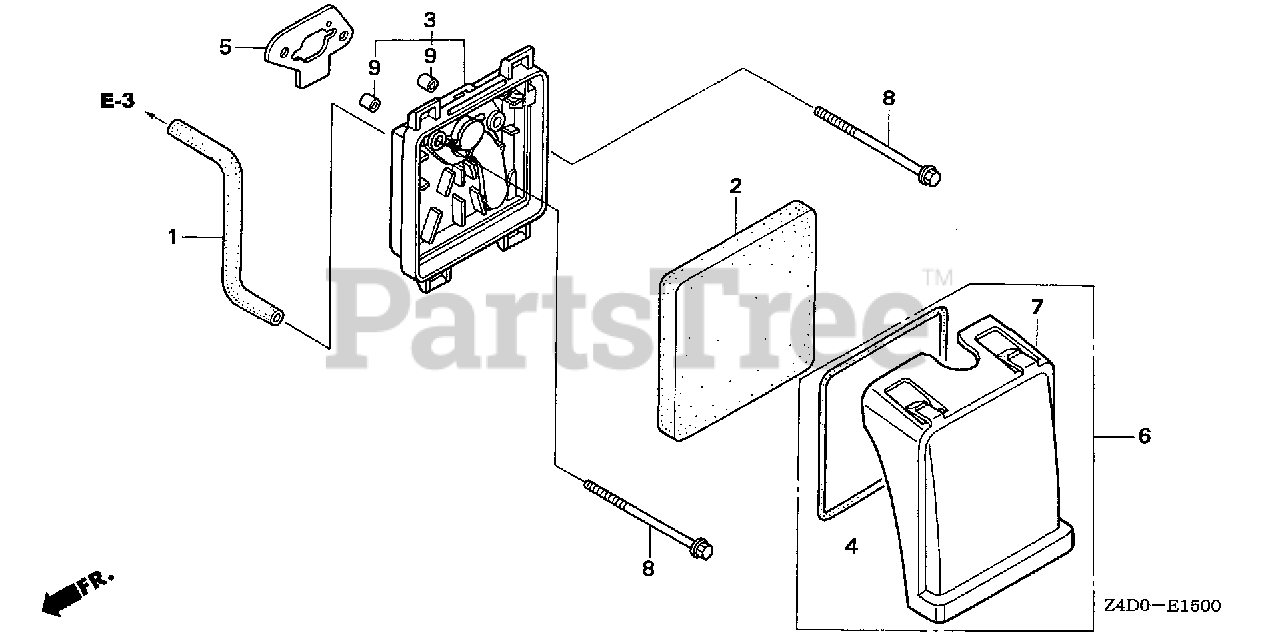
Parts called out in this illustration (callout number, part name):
1	TUBE, BREATHER
2	ELEMENT, AIR CLEANER
3	HOUSING, AIR CLEANER
4	SEAL, AIR CLEANER
5	GASKET, AIR CLEANER
6	COVER, AIR CLEANER
7	COVER, AIR CLEANER
8	BOLT, FLANGE (5X65)
9	COLLAR, AIR CLEANER
